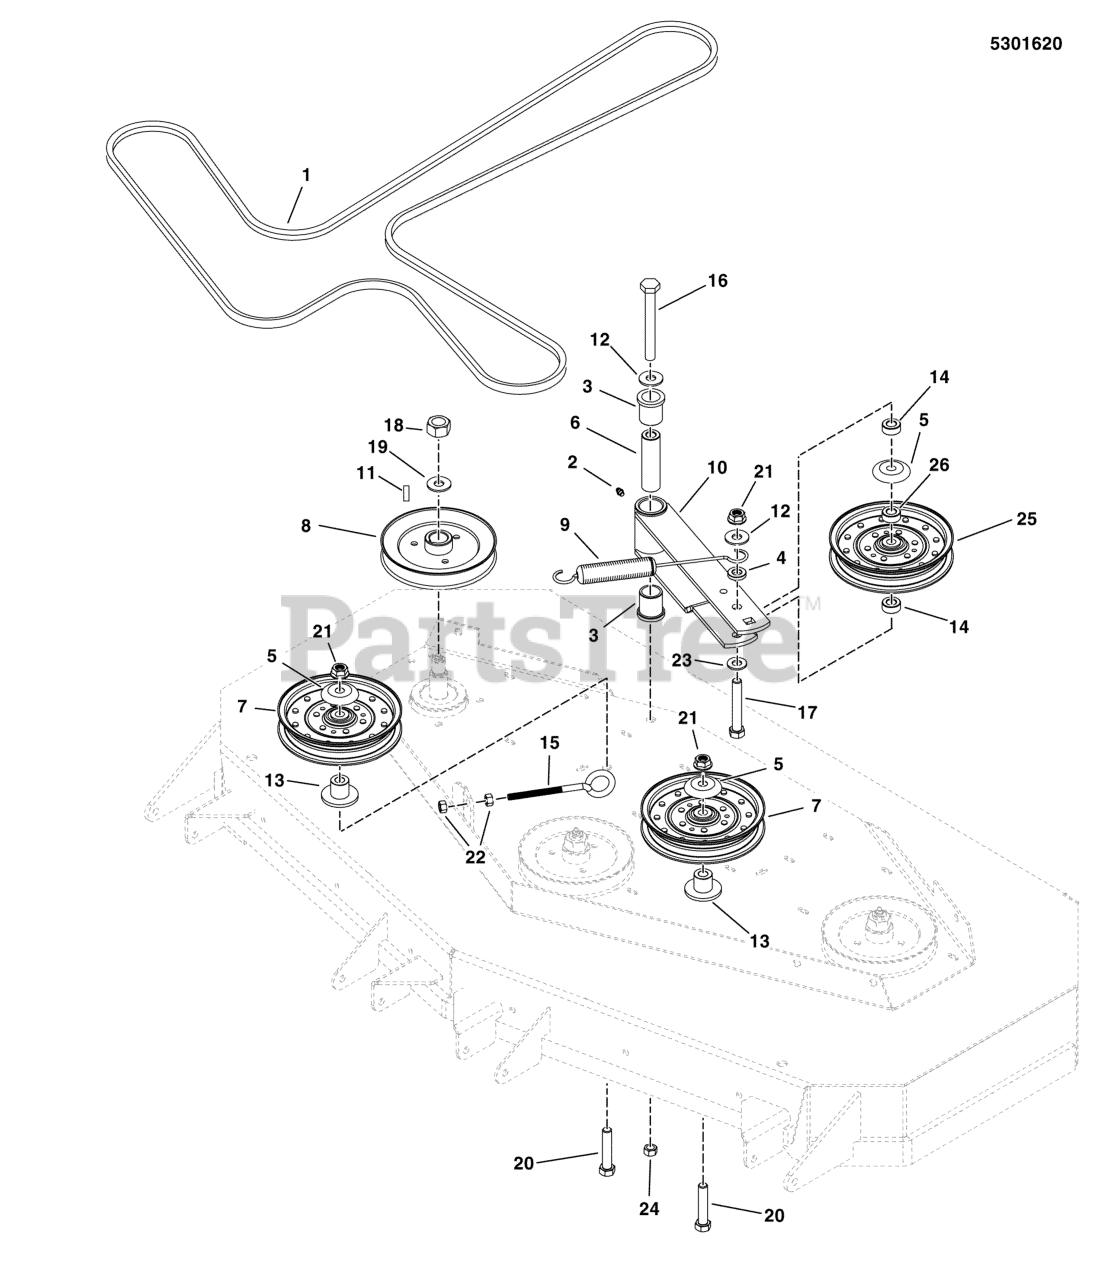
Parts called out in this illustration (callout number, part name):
1	BELT, 5V, 182.00"EL, LRG ARAMID, WRP, RC
2	GREASE FITTING, 45 DEGREE
3	BUSHING, FLANGE
4	SPACER, .52 X 1.00 X .22, PM, CZ
5	SHIELD, PULLEY BEARING
6	SPACER, .52 X 1.00 X 3.50
9	SPRING-EXTENSION, SWIVEL END
10	WELD, IDLER ARM - BLK
11	KEY, 1/4 SQ X 1-1/4
12	WASHER, 1/2 USS
13	IDLER MOUNT
14	SPACER, .52 X 1.00 X .44
15	EYE BOLT, 3/8-16 X 6.88, 3THRD, 1EYE
16	BOLT-1/2-13 X 5 GD5 YZ
17	BOLT, 1/2-13 X 3-1/4, HEX HD, GD5, CZ (SV)
18	NUT, 3/4-16 HEX
19	WASHER, 3/4 BELLEVILLE
20	BOLT, 1/2-13 X 2-1/2" GD5 CZ
21	NUT, Hex Flange, Nylock, 1/2-13
22	NUT, 3/8-16 HEX, YZ
23	WASHER, 1/2 SAE
24	NUT, 1/2-13 HEX NYLON LOCK
25	PULLEY, IDLER - 5
26	INSERT, BEARING
